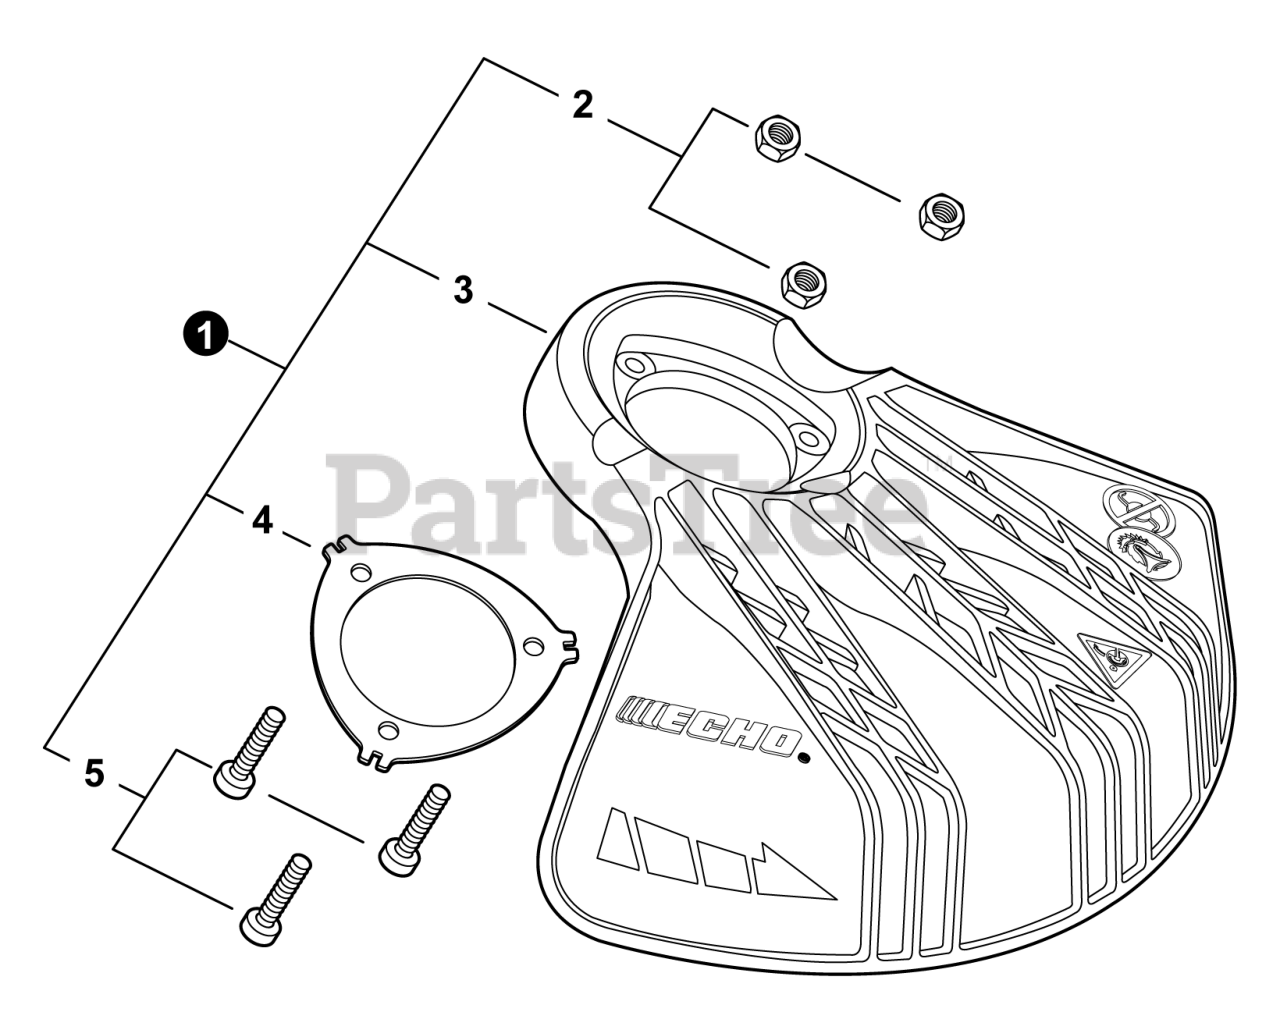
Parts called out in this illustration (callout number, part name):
1	SHIELD KIT, DEBRIS - BLADE
2	NUT, LOCK M5
3	SHIELD, DEBRIS - BLADE
4	PLATE, SHIELD
5	BOLT, TORX 5x25
